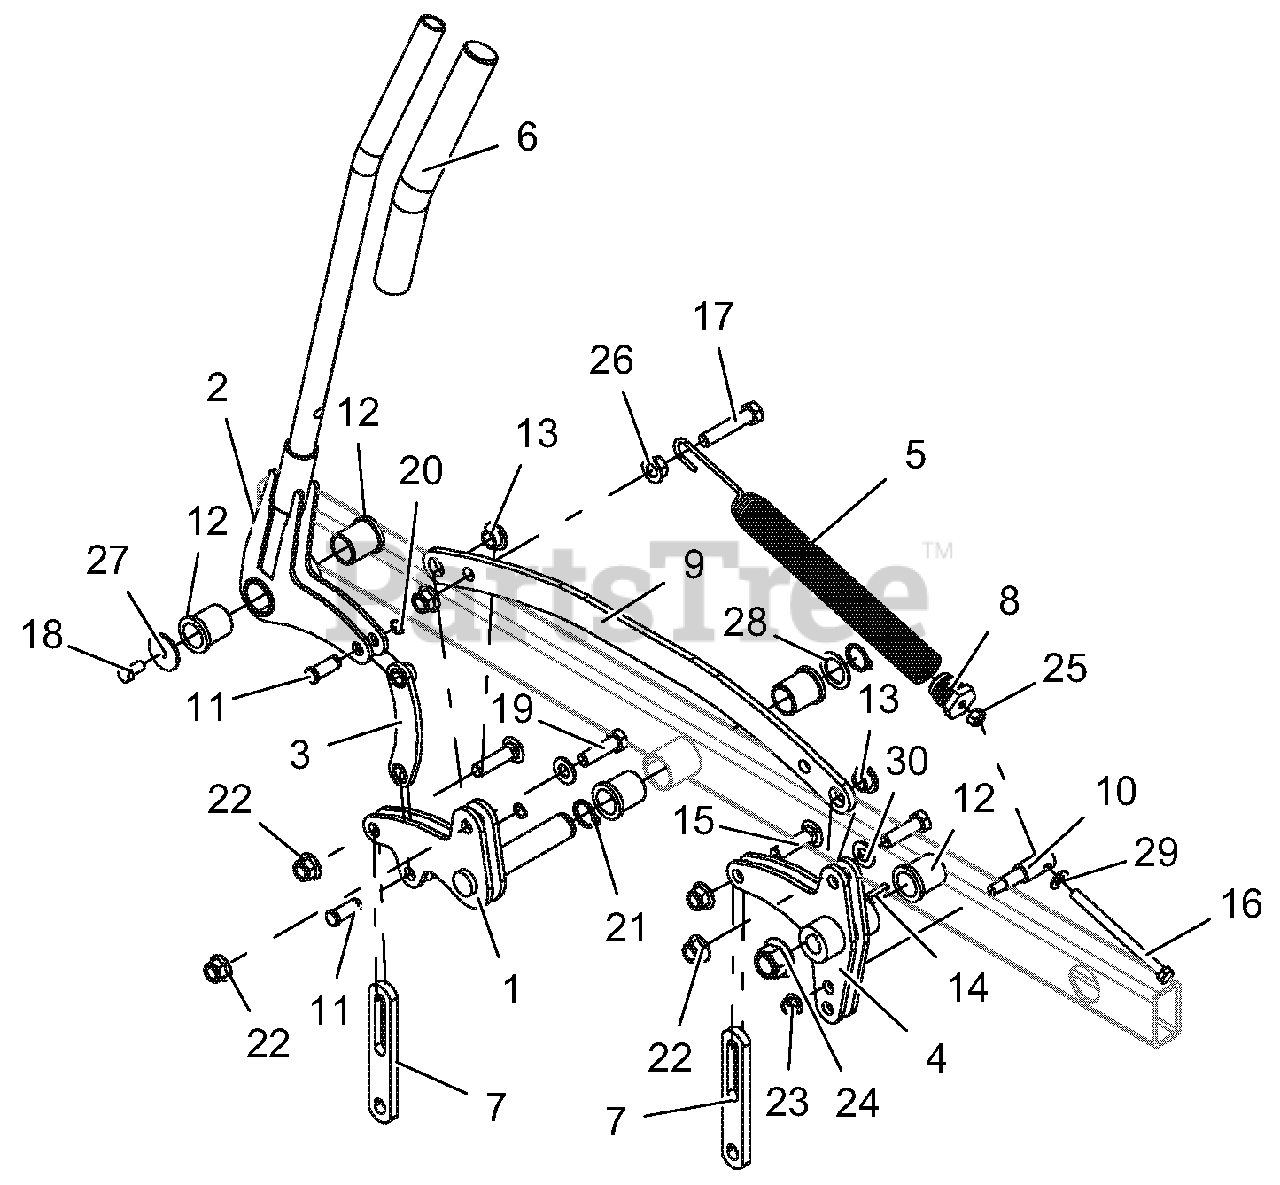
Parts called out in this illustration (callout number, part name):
1	WLDMT, DECK LIFT PROSTANCE
2	WLDMT, HAND LEVER
3	WLDMT, DECK LIFT LINK
4	WLDMT, TAPERED HUB PROSTANCE (BLACK)
5	SPRG, DECK LIFT
6	GRIP, HANDLEBAR
7	LINK, DECK LIFT - LONG
8	PLUG, SPRG
9	ARM, DECK LIFT
10	TRUNION, DECK LIFT
11	PIN, CLEVIS .500 SNAP RING
12	BSHG-FLG 1.00X1.25X1.5X1.5
13	BSHG, FLANGE .515X.750X.420X1.12
14	KEY, WDRF .25 X 1.00 HRD #15
15	BLT-RDHDSQNK .50-13X2.00 G5 Y
16	BLT-HEX .38-16X5.00 GR5 YWZC
17	BLT-HEX .50-13X2.50 GR5 YWZC
18	BLT-HEX .38-16X.75 GR5 YWZC
19	BLT-HEX .50-13X1.75 GR5 YWZC
20	RG-RTNG-EXT .500x.050
21	RG-RTNG-EXT 1.00X.078
22	NUT-LK-NYL-FLG .50-13 YWZC
23	NUT-LK-NYL-FLG .38-16 YWZC
24	NUT-LK-NYL-FLG .75-10 YWZC
25	NUT-HEX .38-16 YWZC
26	NUT .50-13 WIZ FLANGE
27	WSHR-FL-STL .380X1.50X.125 YWZC
28	WSHR-FL-STL 1.010X1.505X.062 YWZC
29	WSHR-FL-STL.406X.812X.065 YWZ
30	WSHR-FL-STL.531X1.06X.095YWZC
